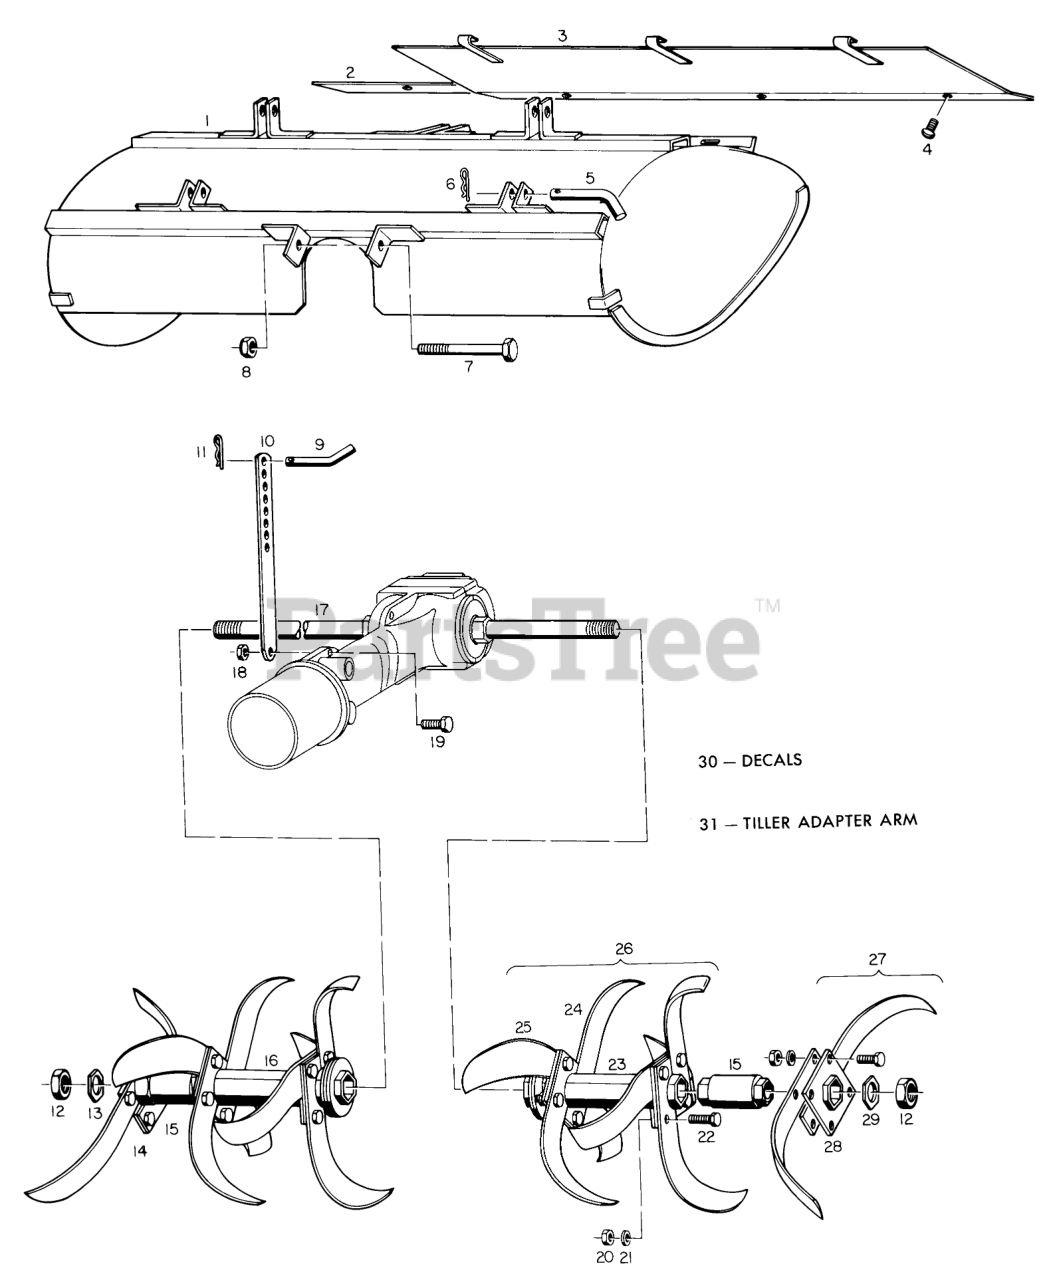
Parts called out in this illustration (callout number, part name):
1	Hood Assembly
2	Ballast Plate
3	Rear Drag Plate
4	Screw
5	"L" Clevis Pin
6	Hairpin Cotter
9	"L" Clevis Pin
10	Adjusting Lever
11	Hairpin Cotter
13	Lockwasher
14	R. H. Outside Tine Assembly, Same as 27, except with two #24 Left Hand Tines
15	Spacing Hub
16	R. H. Inside Tine Assembly (Consists of Parts 20-25)
17	Tine Shaft
21	Washer
23	Tine Carrier Plate Assembly
24	Left Hand Tine
25	Righ Hand Tine
26	L.H. Inside Tine Assembly (Consists of Parts 20-25)
27	L.H. Outside Tine Assembly (Consists of 20, 21, 22, 28 and 29)
28	Carrier Plate Assembly
29	Lockwasher
30	Caution Decal
30	Decal
31	Adapter Arm
